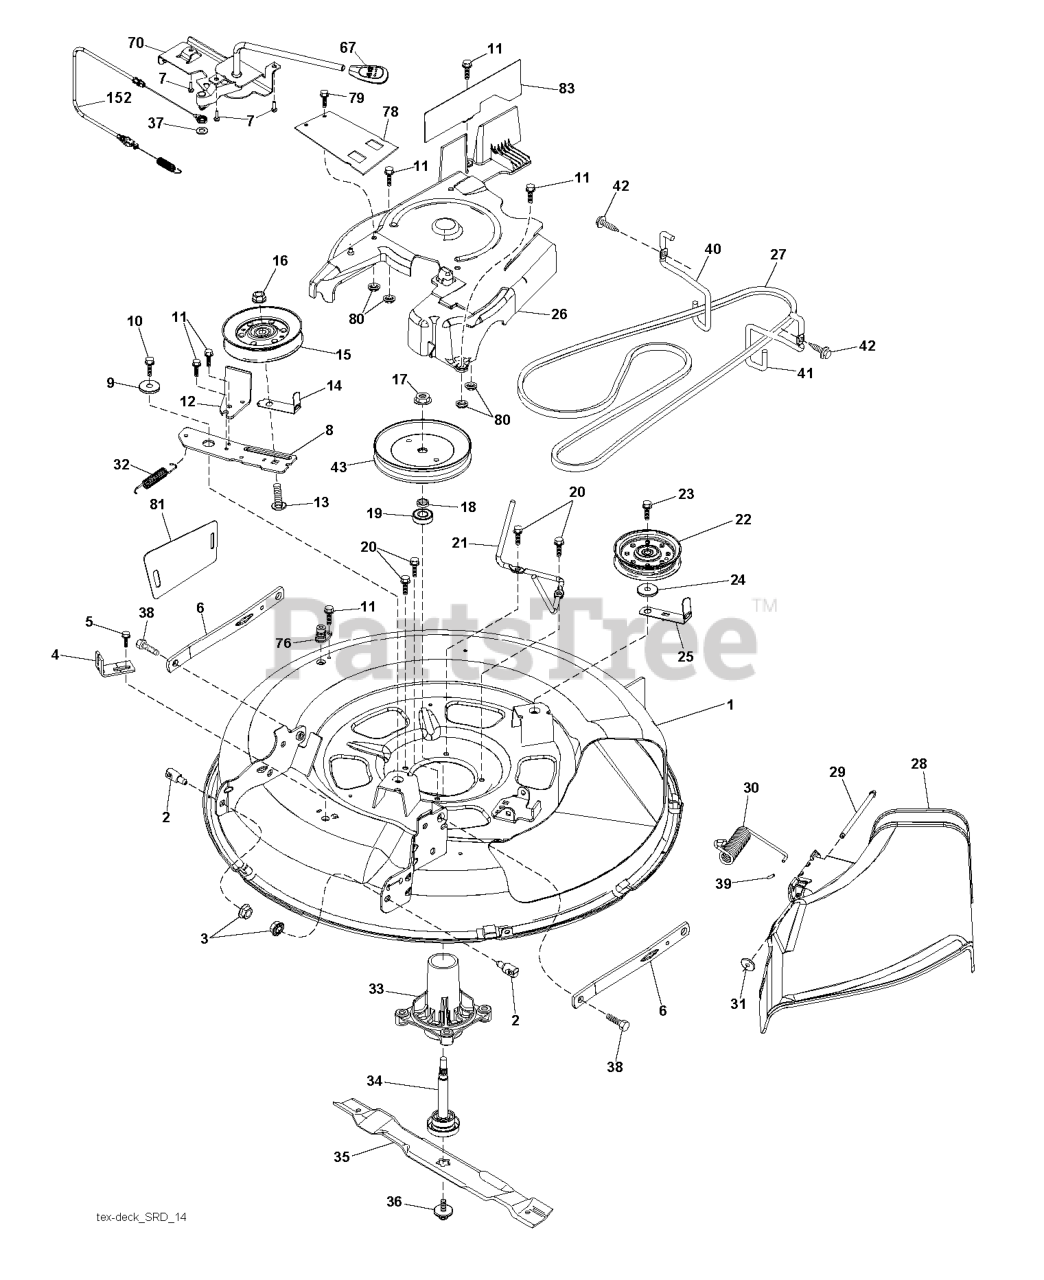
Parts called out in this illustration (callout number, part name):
1	DECK.WELDMENT.30"SRD.BLACK
2	STUD.FASTNER.W/ANTI-ROTATE
3	NUT LOCK HEX FLANGE 5/16-18
4	BRACKET.CLUTCH.CABLE
5	BOLT.5/16HEX.WHS.HD
6	ARMS.SUSP.MOWER.REAR.SRD
7	SCREW.#10 X 0.750.BOS
8	ARM.IDLER.30"SRD
9	SPACER.RETAINER
10	SCREW 3/8-16X1
11	SCREW.1/4-20X5/8
12	RP ARM.BRAKE.MOWER.38"LH.TEX
13	BOLT.3/8-16X1.50
14	KEEPER, BELT IDLER
15	PULLEY.IDLER.4.25
16	NUT LOCK FLG 3/8-16 UNC
17	NUT.FLANGE.LOCK.TOP
18	WASHER.SPACER.MANDREL
20	SCREW, WASHER HEAD
21	KEEPER.BELT.MANDREL.30"
22	PULLEY.IDLER.FLAT.UNPLATED
23	SCREW LT
24	WASHER
25	KEEPER.BELT.30"SRD
26	COVER.ASM.MANDREL.30"
27	V-BELT.DRIVE.MOWER.30"
28	SHIELD.DEFLECT.MWR.30S.BLACK
29	PIN.HINGE.30".SRD
30	SPRING.TORSION.DEFLECT
31	NUT PUSH M
32	SPRING RETURN
33	RP.HOUSING.MANDREL.4PT.
34	SHAFT.ASM.MDRL.N/GREASE.38
35	BLADE, MULCH.LRV30
36	BOLT.WASHER.ASM.7/16-2
37	WASHER
38	BOLT.SHOULDER
39	CAP-SLEEVE LT
40	KEEPER.BELT.ENGINE.LH.LT.SRD
41	KEEPER.BELT.ENGINE.RH.LT.SRD
42	SCREW, 3/8-16X3/4
43	PULLEY, MANDREL 6.5 PD
67	HANDLE.CLUTCH.CABLE.LT
70	CLUTCH.ASM.MANUAL.LT.PRED
76	PORT.WASHOUT
78	GUARD ARM CLUTCH
79	SCREW.HI-LO.CONSOLE
80	PALNUT 1/4
81	SHIELD SUSPENSION
83	GUARD LEFT
152	CLUTCH CABLE
